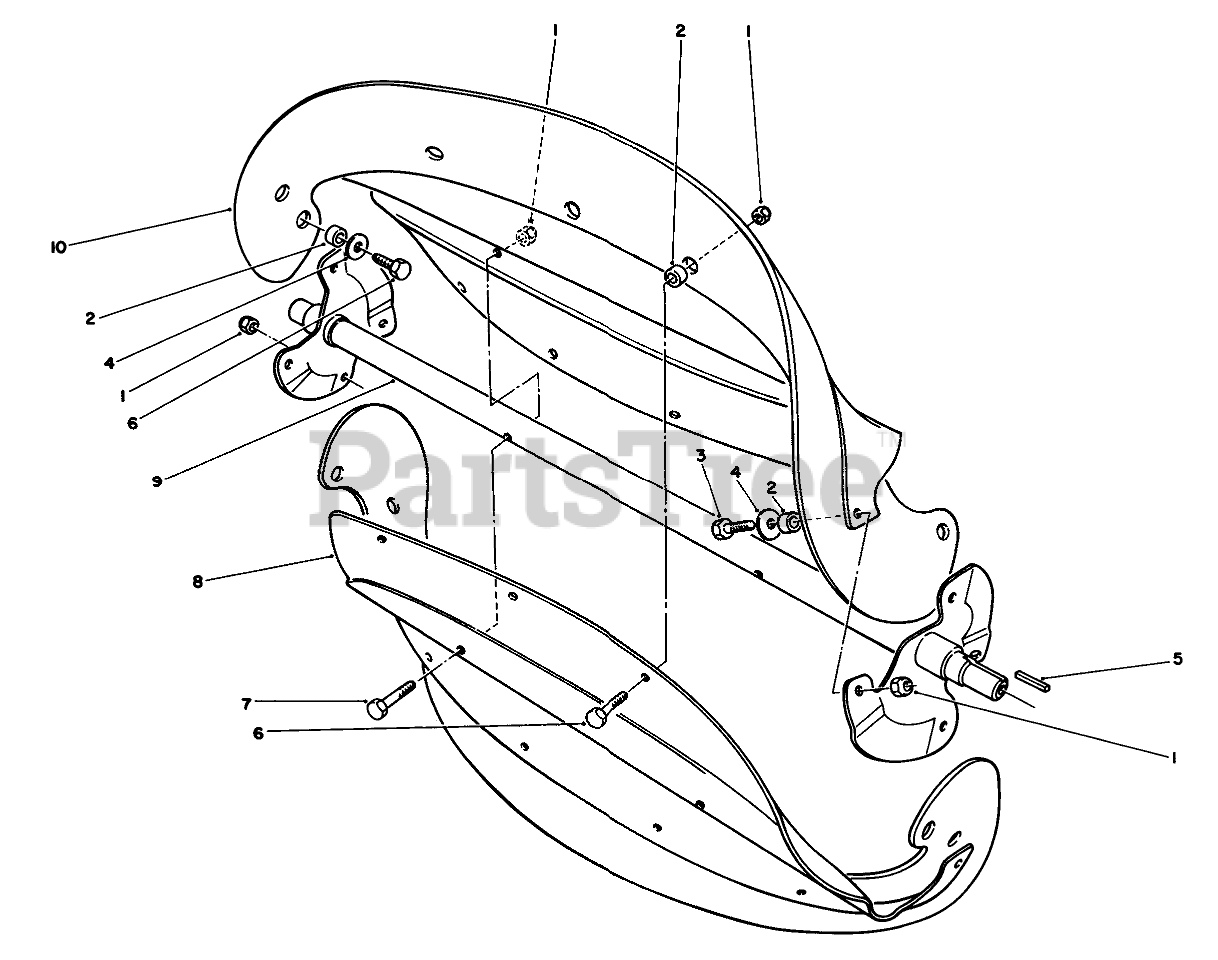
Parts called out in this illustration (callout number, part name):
1	NUT-LOCK, NI
2	SPACER-BLADE, ROTOR
3	SCREW-HH
4	WASHER-FLAT
5	KEY-SQUARE
6	SCREW-HH
7	SCREW-HH
8	ROTOR
9	Rotor Shaft Assembly
10	Blade-Rotor
